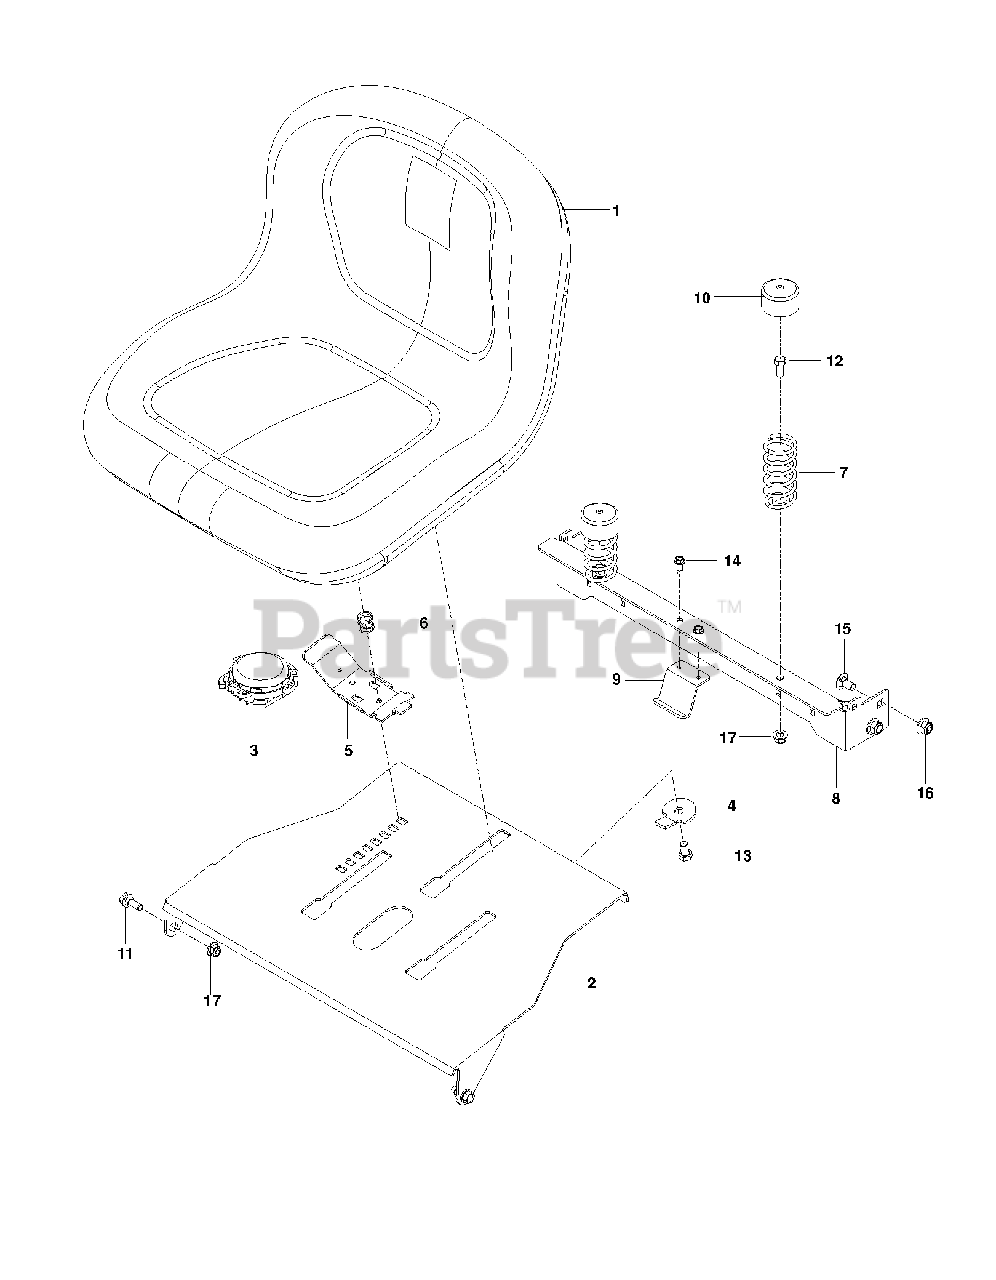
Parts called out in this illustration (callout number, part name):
1	SEAT.TH150.MS498.GRY.HUSQ.TEX
2	PLATE, SEAT, ORG
3	SWITCH, SEAT N/C
4	STOP, SEAT, BLACK
5	HANDLE.SLIDE.SEAT.TEX.BLACK
6	SPRING.LATCH.SEAT.TEX
7	SEAT SPRING
8	SEAT SUPPORT, REAR ORG
9	HCS 3/8-16 X 5/8 GR 5 ZD
9	HOLDING DEVICE, FUEL TANK, BLK
10	SPRING CAP
11	BOLT, SHOULDER
12	HCS 5/16C X 3/4
13	HCS 3/8-16 X 5/8 GR 5 ZD
14	SCREW 1/4 X 5/8
15	RHSNB 3/8-16 X 3/4 GR5 ZD
16	NUT 3/8-16 HEX FLG NYLOC ZD
17	5/16-18 NYLOC FLANGE NUT
